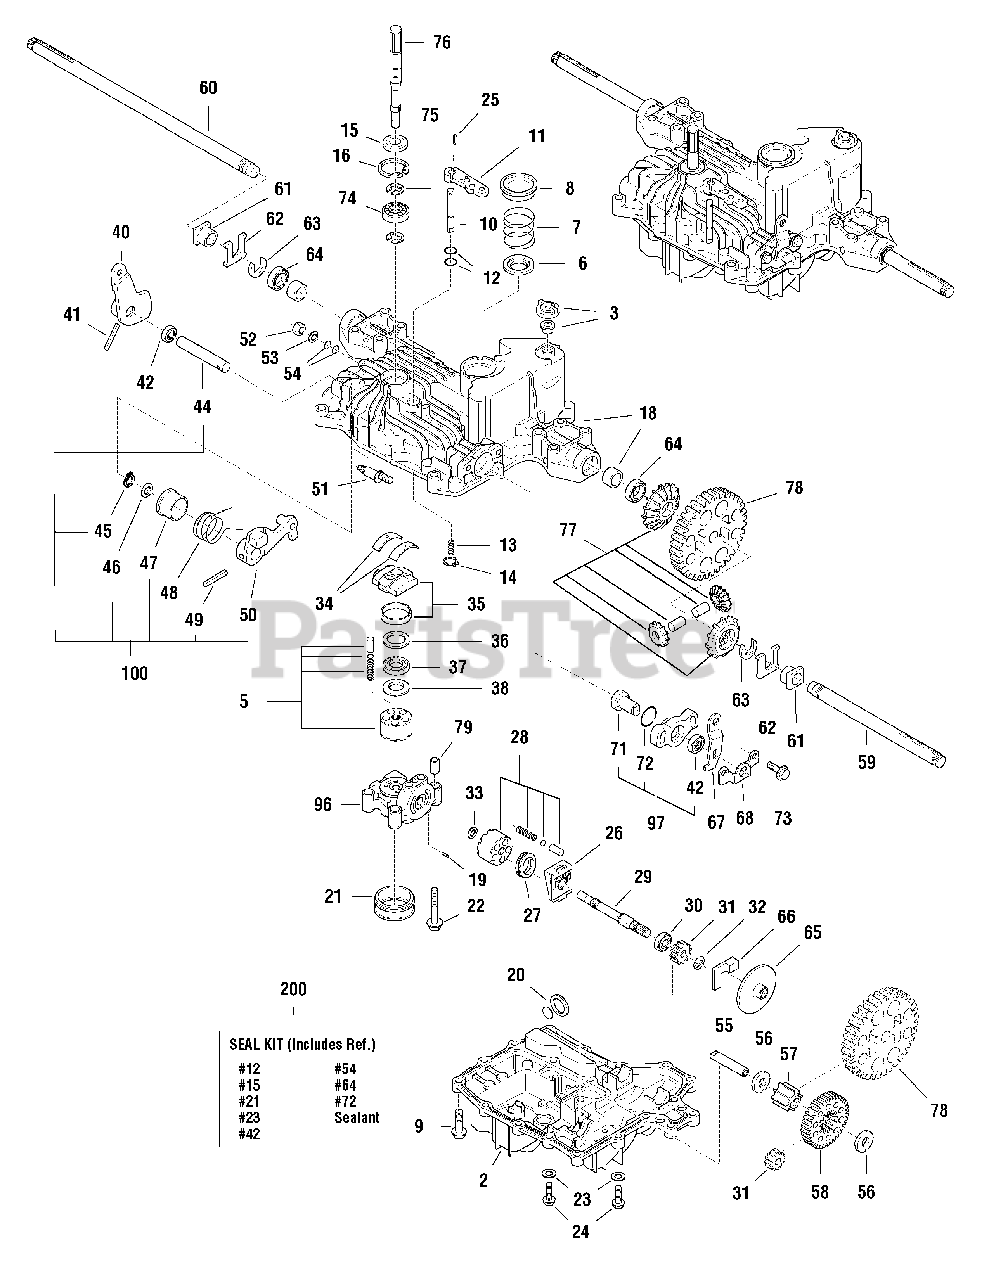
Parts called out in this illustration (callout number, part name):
2	HOUSING, LOWER TUFF TORQ
3	VENT VALVE, 15 (includes Ref. Nos. 78 & 79)
5	CYLINDER BLOCK
6	FILTER, DISC
7	SPRING, FILTER
8	SEALING CAP, 50
9	SCREW, TAPPING
10	SHAFT, BYPASS
11	LEVER, BYPASS
12	O-RING, 1A P10A
15	SEAL
18	HOUSING, UPPER ASSEMBLY, Complete (Includes Ref. Nos. 76 & 77)
19	PIN, 3 x 9.8
21	FILTER, 40U
22	BOLT, 10 60
23	WASHER, SEAL 8
27	BEARING, 51106
28	CYLINDER BLOCK
29	SHAFT, MOTOR
30	BEARING, 6202UC3
33	WASHER, 12 x 24 x 1
34	THRUST METAL
35	SWASH PLATE ASSEMBLY
36	THRUST PLATE, B
37	BEARING, K81105
38	THRUST PLATE, A
40	LEVER, CONTROL
41	PIN, 6.0A x 4.0
42	SEAL, TC162606
44	SHAFT, CONTROL
47	COLLAR, CONTROL
48	SPRING, TORSION
49	PIN, 6.0A x 25
50	*CONTROL ARM, B
51	*FULCRUM ECCENTRICITY
55	*SHAFT, Reduction
57	PINION, FINAL
58	*GEAR, Reduction
59	*AXLE SHAFT, Left
60	AXLE SHAFT, Right
61	BUSHING, 19 x 21
62	WASHER, Thrust
64	SEAL, 19 x 32 x 8
66	SHOE, Brake
67	*ARM, Brake
68	*PLATE, Brake
71	SHAFT, Brake
72	PACKING, P29
75	RING, E15
76	PUMP SHAFT, Tapered
77	GEAR KIT, Differential
78	GEAR, Final
79	KNOCK PIN, 12 x 22
96	CASE, CENTER A
97	KIT, Brake Cam
100	SHAFT ASSEMBLY, Control
200	K51/K56 SEAL KIT
